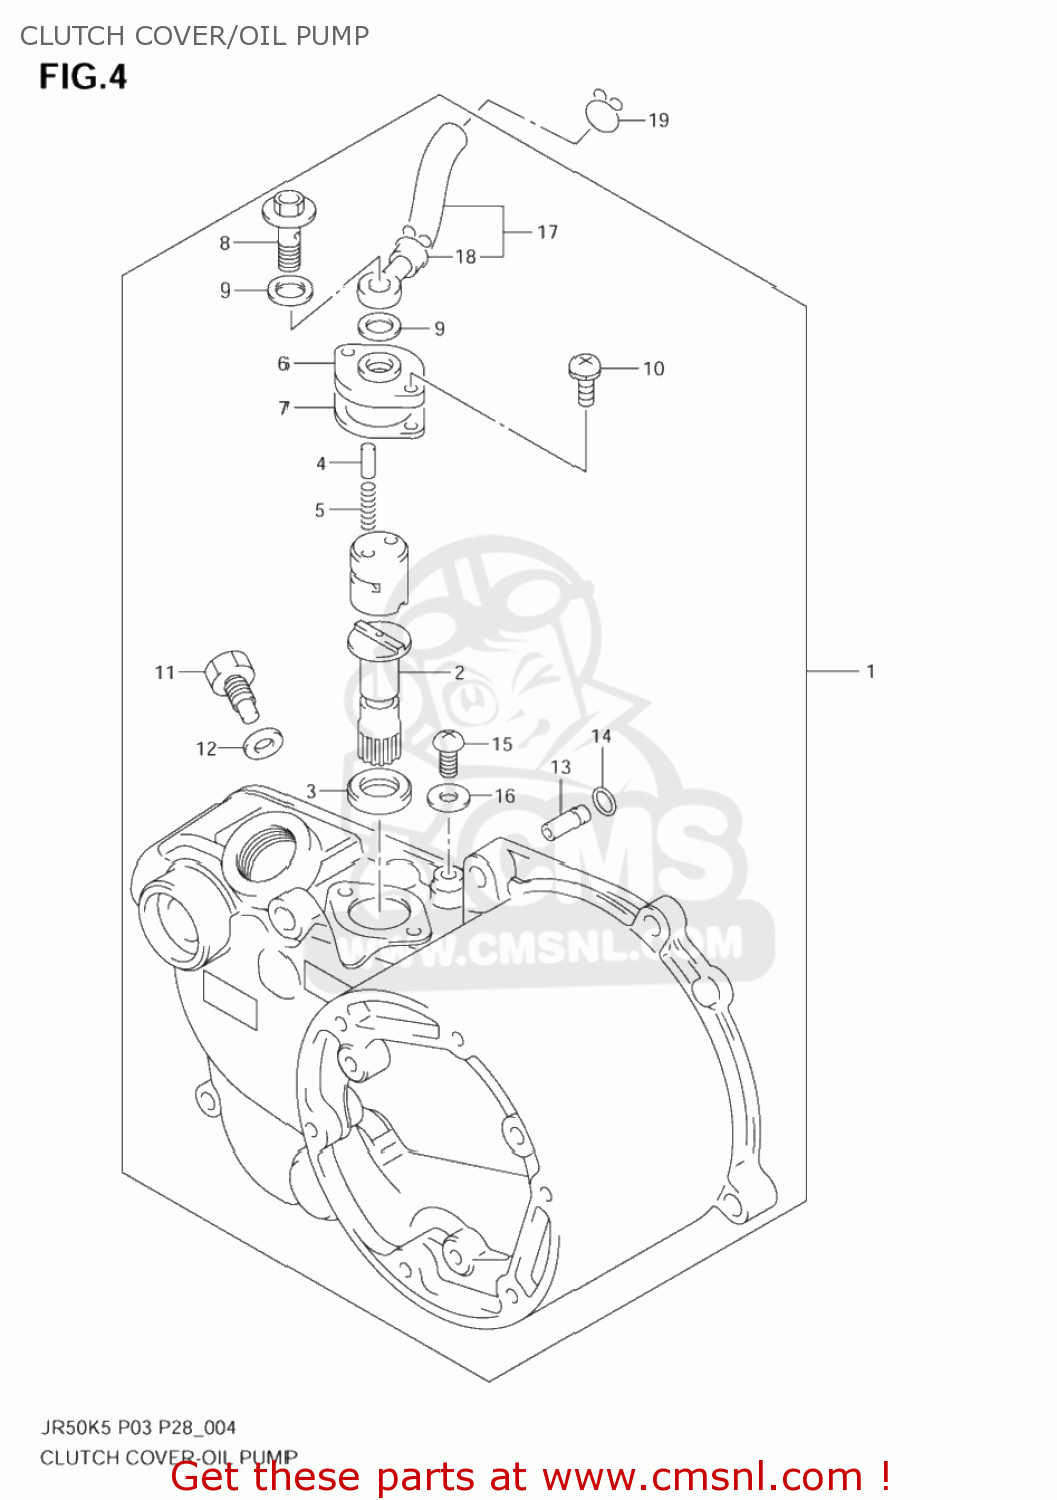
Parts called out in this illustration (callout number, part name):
1	COVER SET, CLUTCH
2	GEAR,OIL PUMP DRIVE
3	SEAL,OIL(12X18.5X3)
4	PIN(2.3X7.5)
5	SPRING
6	CAM,OIL PUMP
7	GASKET,OIL PUMP (NAS)
8	UNION BOLT
9	GASKET(6.2X11X1).2 (NAS)
10	SCREW
11	BOLT(6X10)
12	WASHER
13	VALVE,CRANK CHECK
14	O RING(D:1.05,ID:3.1)
15	SCREW
16	GASKET(5X9.5X1) (NAS)
17	HOSE,INLET
18	CLIP
19	CLIP
